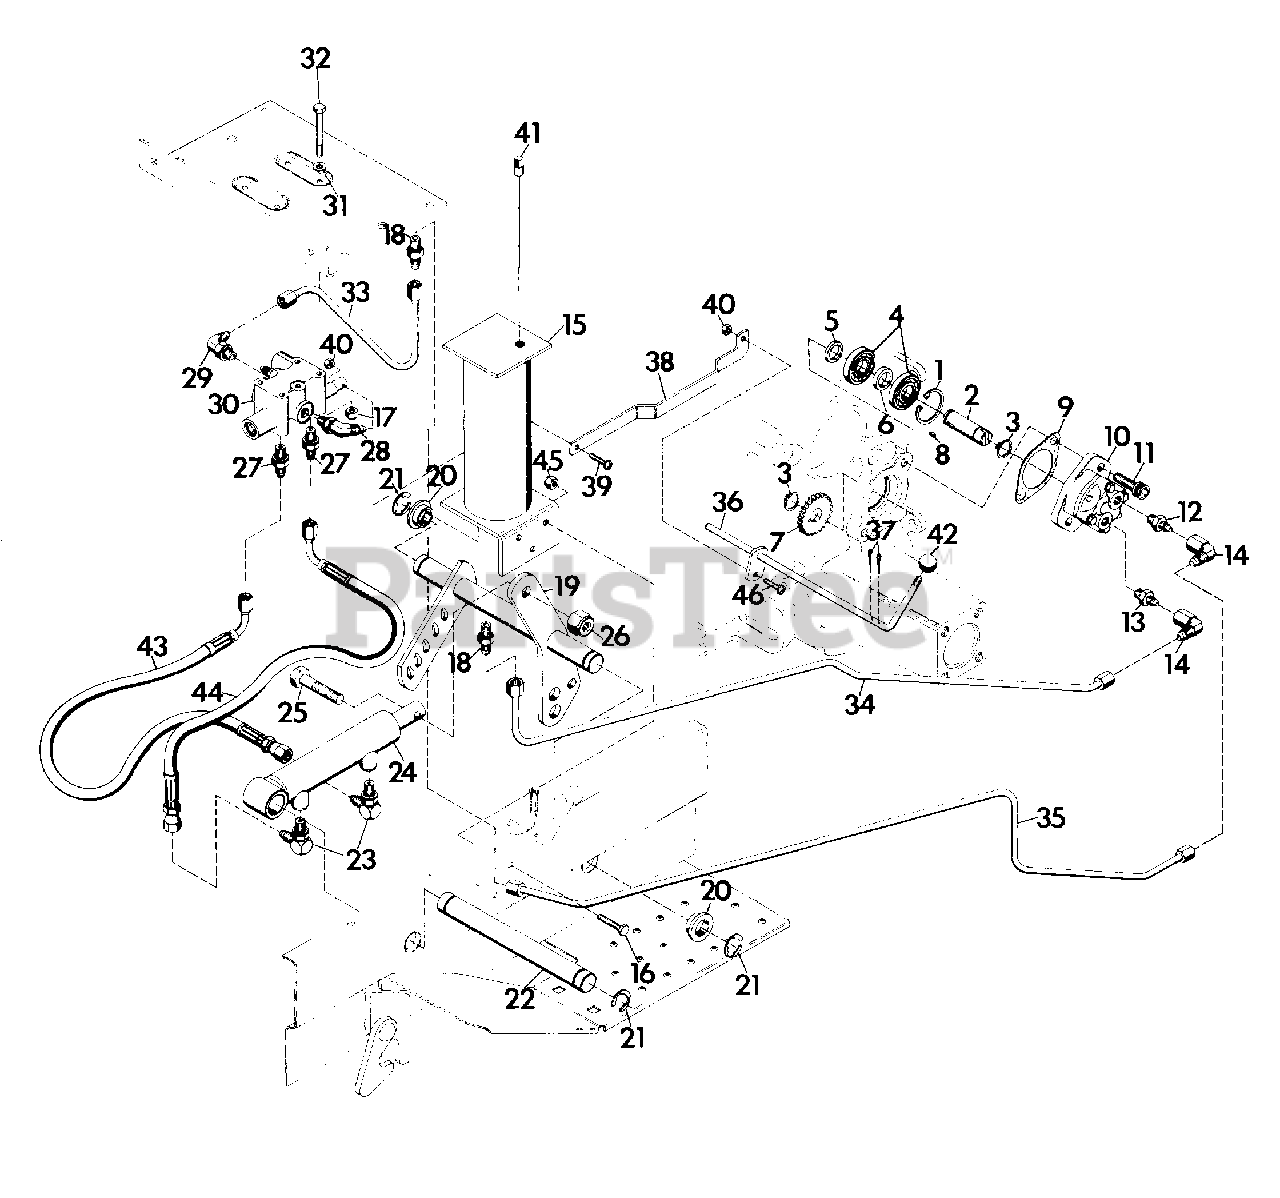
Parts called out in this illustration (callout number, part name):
1	RING, RETAINING 1.378 BORE
2	SHAFT, HYDRAULIC PUMP
3	RING, RETAINING .594 SHAFT
4	BEARING, BALL .590X1.378X.433
5	SPACER, .620X.750X.276
6	SPACER, .620X.750X.364
7	GEAR, HYDRAULIC PUMP
8	KEY, WOODRUFF .125X.375 HARD
9	GASKET, COVER PLATE
10	PUMP, HYDRAULIC
11	SCREW, CAP 3/8-16 HEX SOCKET HD
12	ADAPTOR
13	ADAPTOR(P-H #0503-10-6)
14	ADAPTOR(P-H #3903-6-6)
15	WELDMENT, HYDRAULIC TANK
16	BOLT, HEX 3/8-16X1
17	NUT, LOCK 1/4-20
18	ADAPTOR(P-H #0503-6-6)
19	WELDMENT, LIFT LEVER SHAFT
20	BUSHING, PIVOT
21	E-RING, 1.000 SHAFT
22	SHAFT, HYDRAULIC CYLINDER
23	ADAPTOR(P-H #2503-4-4)
24	CYLINDER, HYDRAULIC
25	BOLT, HEX 1/2-13X2.00
26	NUT, LOCK 1/2-13
27	ADAPTOR(P-H #0503-4-4)
28	ADAPTOR(P-H #3503-6-6)
29	ADAPTOR(P-H #2503-6-6)
30	VALVE, HYDRAULIC
31	WASHER, FLAT .281X.625X.065
32	BOLT, HEX 1/4-20X2-3/4
33	LINE, RETURN VALVE TO TANK
34	LINE, HYD.(IN) TANK TO PUMP CONS.
34	LINE, HYD.(IN) TANK TO PUMP PROF.
35	LINE, HYD.(OUT) VALVE TO PUMP CONS.
35	LINE, HYD.(OUT) VALVE TO PUMP PROF.
36	ROD, WELDMENT HYD. VALVE
37	PIN, COTTER .094X.75
38	ROD, HYDRAULIC CONTROL
38	ROD, HYDRAULIC CONTROL PROF.
39	SCREW, MACHINE 10-24X1 RD HD
40	NUT, LOCK 10-24
41	GAUGE, HYDRAULIC TANK LEVEL
42	KNOB, ADJ. CONTROL
43	HOSE, HYDRAULIC 12.5
44	HOSE, HYDRAULIC 9.5
45	NUT, LOCK 3/8-16
46	SCREW, MACHINE 10-24X3/4 RD HD
